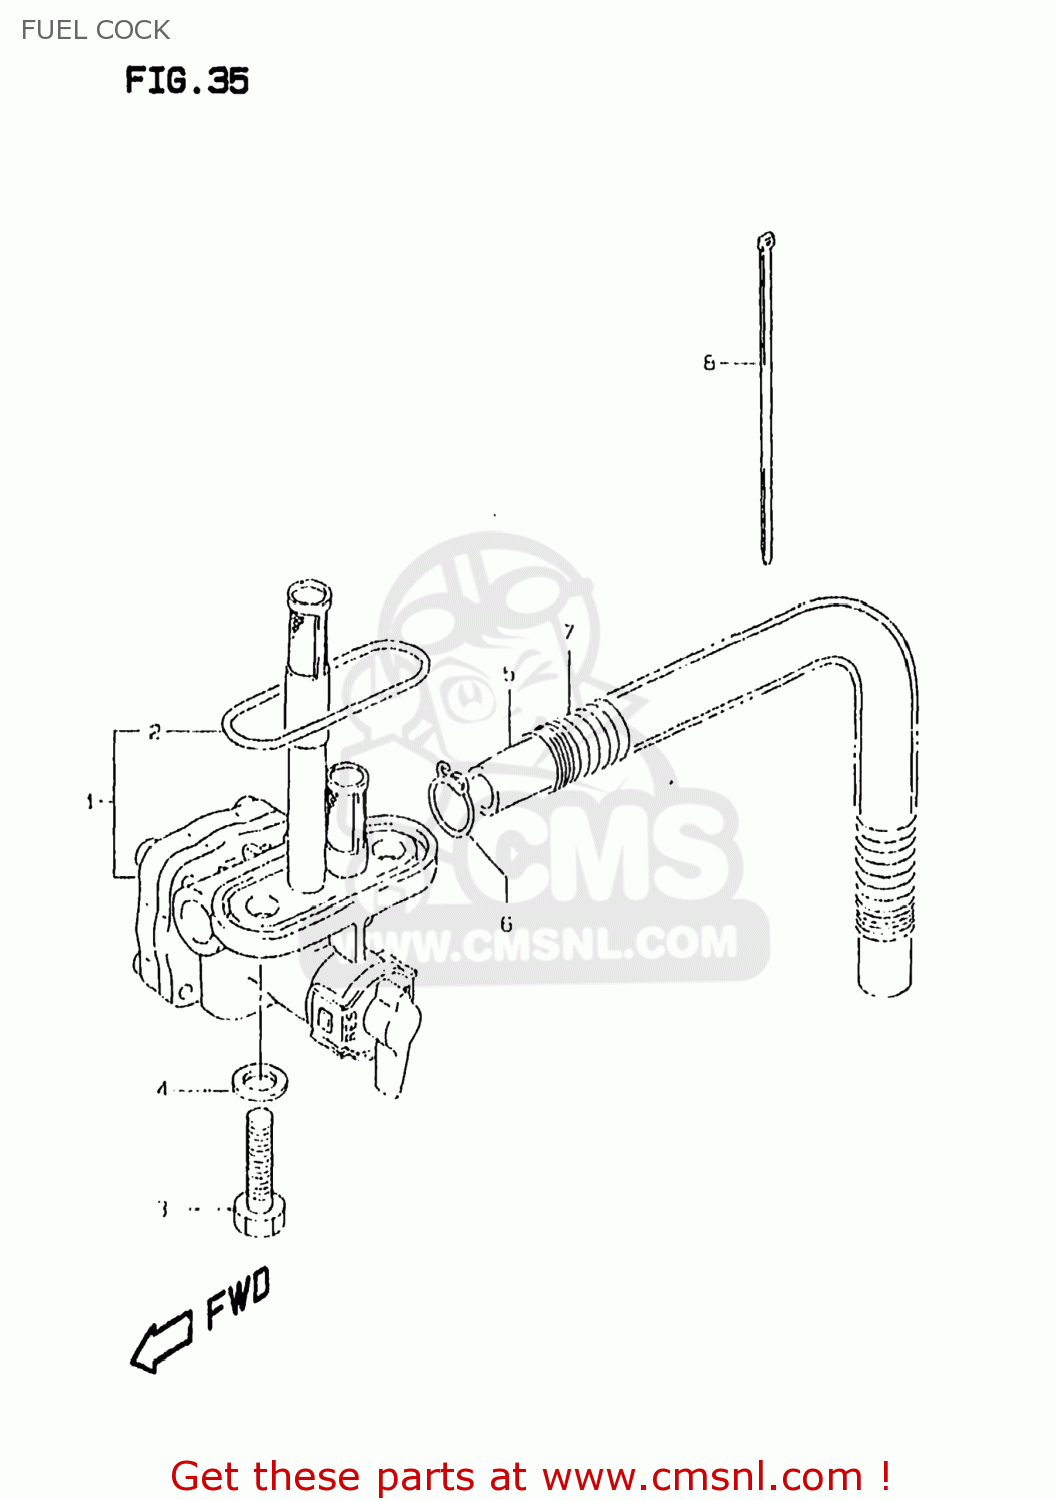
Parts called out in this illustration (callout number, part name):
1	COCK ASSY,FUEL
2	GASKET,JOINT (NAS)
3	BOLT(6X20)
4	GASKET(6.4X11.5X0.8) (NAS)
5	HOSE(7X12X600)
6	CLIP
7	SPRING
8	CLAMP(L:45)
